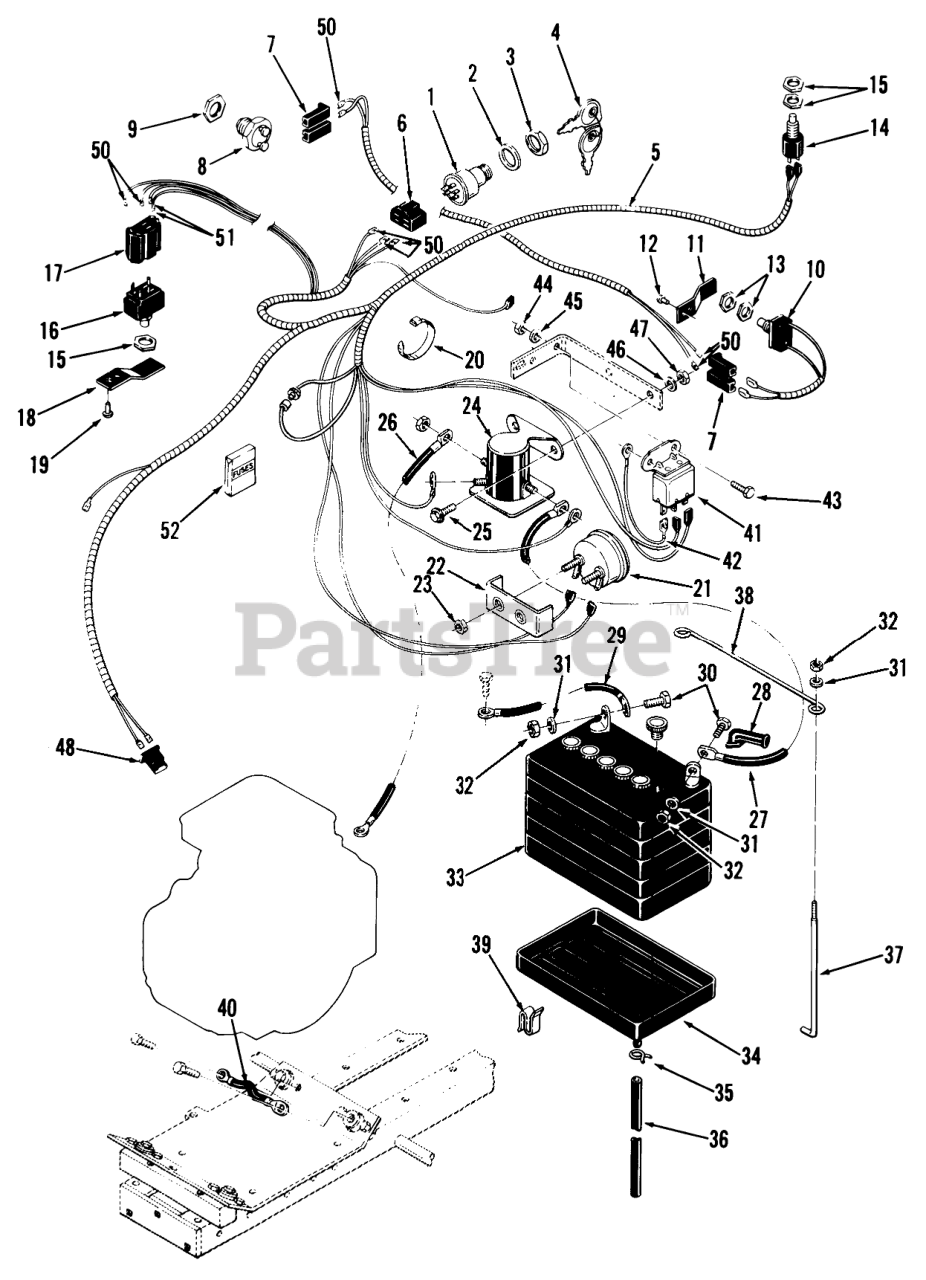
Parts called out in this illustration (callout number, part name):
1	SWITCH-IGNITION
2	LOCKWASHER
4	Key-EL
5	WIRE HARNESS
5	WIRING HARNESS ASSY
6	CONNECTOR-5 WAY-SERV
7	Connector Housing Pedal Switch
8	SWITCH-INTERLOK CLUT
9	NUT-SPECIAL 9/16-18
10	Interlock Switch-Transmission
11	CLIP-SWITCH
12	RIVET
13	NUT-HEX
14	SWITCH
15	NUT-HEX
16	SWITCH-CLUTCH
17	CONNECTOR 5 WAY
18	CLIP-SWITCH
19	RIVET
20	PLASTIC TIE
21	AMMETER W/CLAMP
22	Clamp
23	HEX NUT 10-32 E.S.
24	Solenoid
25	Screw
26	Starter-Solenoid 20 1/2"
26	Cable-Solenoid To Starter
27	Cable
28	Terminal Cover
29	Wire
30	Bolt
32	Nut
33	Battery
34	TRAY-BATTERY
35	Clamp
36	FUEL HOSE 13" OF 6554
37	Hook
38	ROD-HOLD DOWN
39	CLIP
40	Wire
41	Relay
42	RELAY-GROUND WIRE
43	Bolt 10-32 X 5/8
44	Nut
45	Lockwasher Internal
46	LOCKWASHER
47	Nut
48	Conn Body Part of 7
50	Terminal
51	TERMINAL-TAB RCPT
